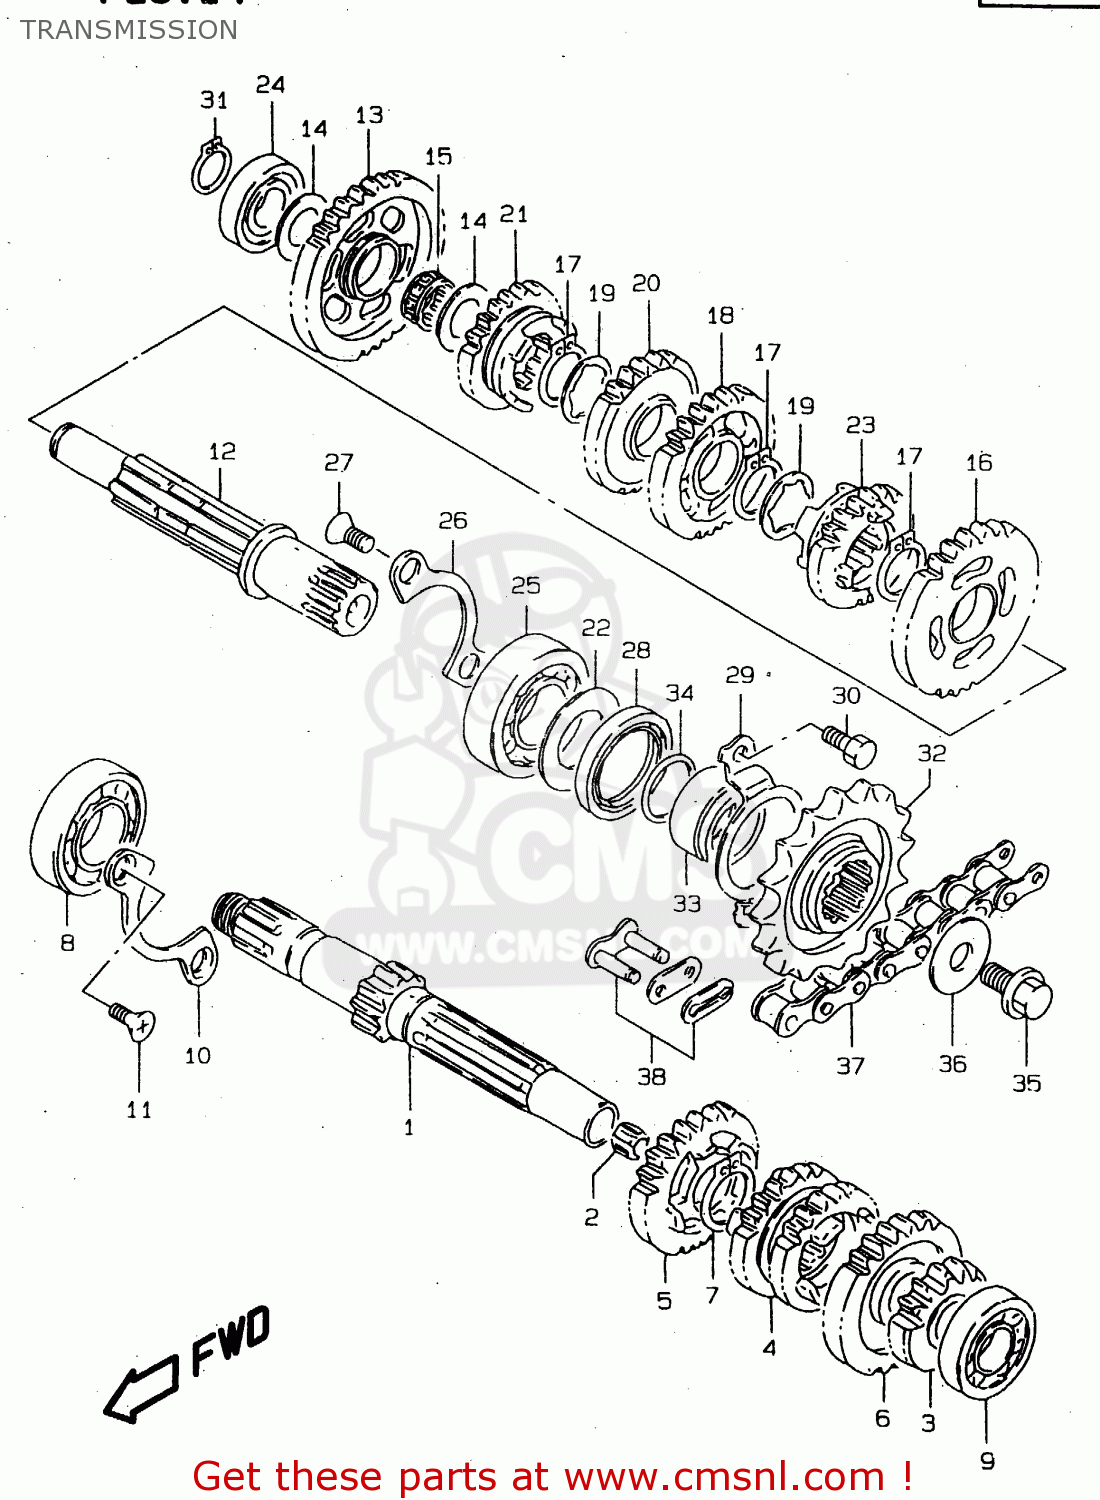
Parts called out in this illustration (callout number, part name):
1	SHAFT,COUNTER (NT:11)
2	BUSH
3	GEAR,SECOND DRIVE
4	GEAR,3RD & 4TH DRIVEN(NT:19/21
5	GEAR,FIFTH DRIVE
6	GEAR,SIXTH DRIVE
7	CIRCLIP
8	BEARING(20X47X14)
9	BEARING
10	RETAINER,DRIVE SHAFT BEARING
11	SCREW
12	SHAFT,DRIVE
13	GEAR,FIRST DRIVEN (NT:33)
14	WASHER
15	BEARING(15X19X7.8)
16	GEAR,2ND DRIVEN(NT:26)
17	CIRCLIP
18	GEAR,THIRD DRIVEN
19	WASHER,LOCK
20	GEAR,FOURTH DRIVEN
21	GEAR,FIFTH DRIVEN
22	WASHER,OIL SEALING
23	GEAR,SIXTH DRIVEN
24	BEARING(15X36X12)
25	BEARING(22X50X14)
26	RETAINER,DRIVE SHAFT BEARING
27	BOLT
28	SEAL,OIL(30X40X6)
29	RETAINER,DRIVESHAFT O
30	SCREW
31	CIRCLIP
32	SPROCKET,ENGINE(NT:16)
33	SPACER,ENGINE SPROCKET
34	O RING(D:2.5,ID:21)
35	BOLT
36	WASHER
37	CHAIN ASSEMBLY,DRIVE
38	JOINT(RK)
